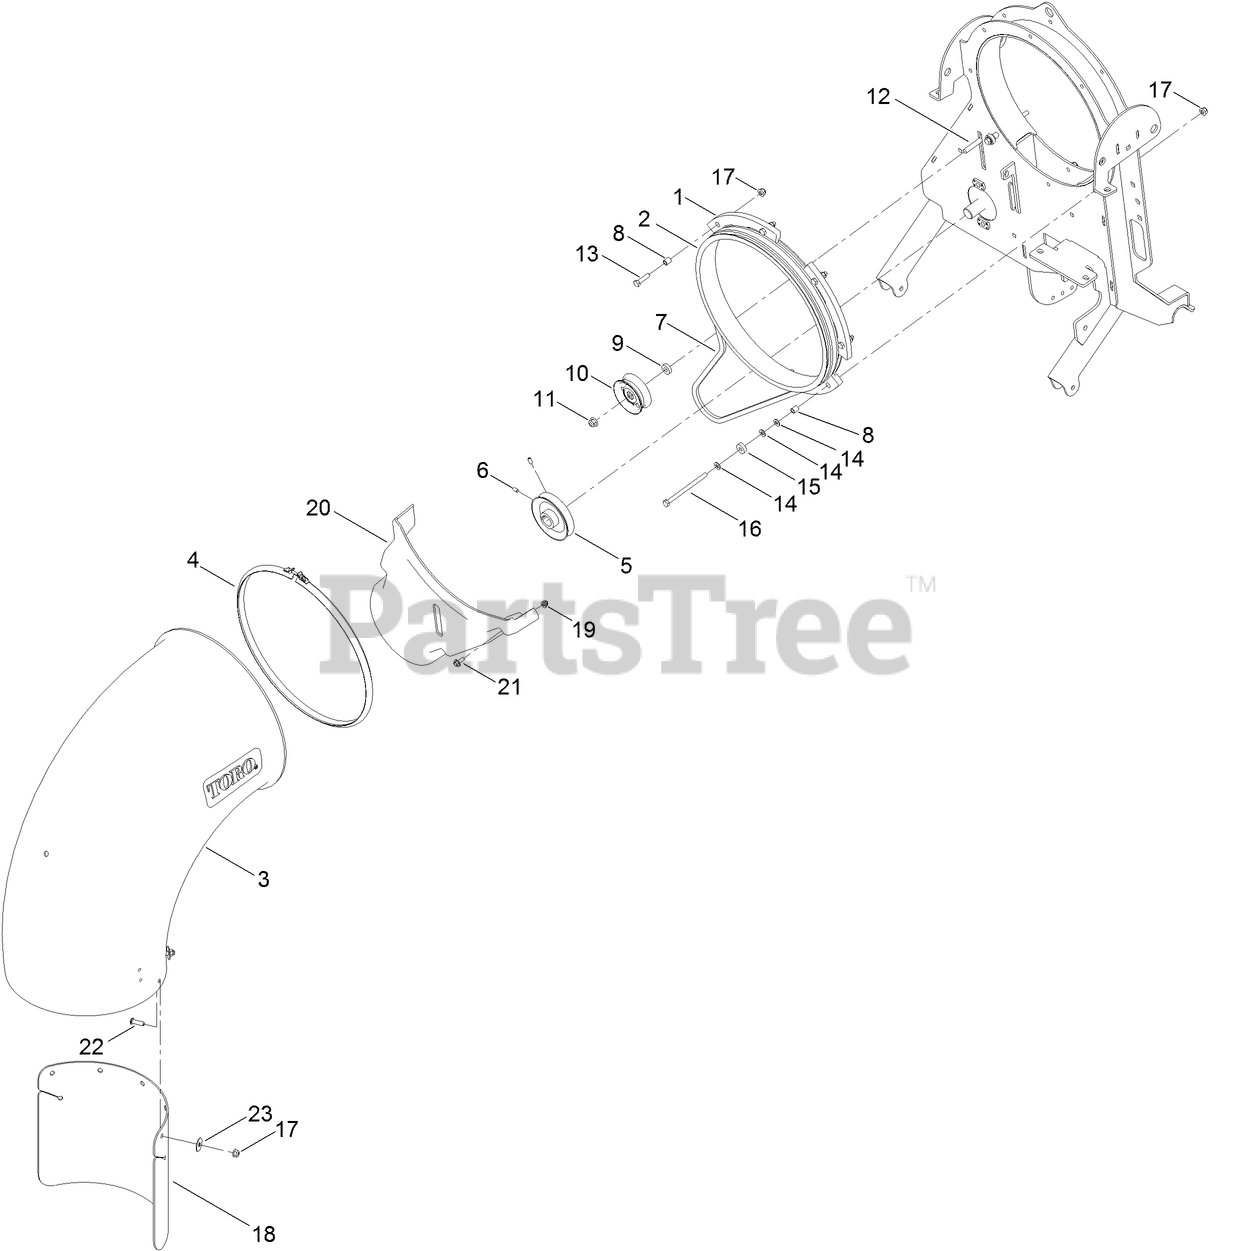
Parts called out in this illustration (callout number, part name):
1	GUIDE-NOZZLE
2	PULLEY-NOZZLE
3	NOZZLE
4	CLAMP-NOZZLE
5	PULLEY
6	SCREW-SET, HSH
7	BELT-V
8	SPACER
9	SPACER
10	PULLEY-IDLER, FLAT
11	NUT-HF, NI
12	BOLT-CARRIAGE
13	SCREW-HH
14	WASHER-FLAT
15	BEARING-BALL
16	SCREW-HH
17	NUT-HF, NI
18	EXTENSION-NOZZLE
19	NUT-CLIP
20	COVER-BELT
21	SCREW-HWH
22	SCREW-HSBH
23	WASHER-FLAT
